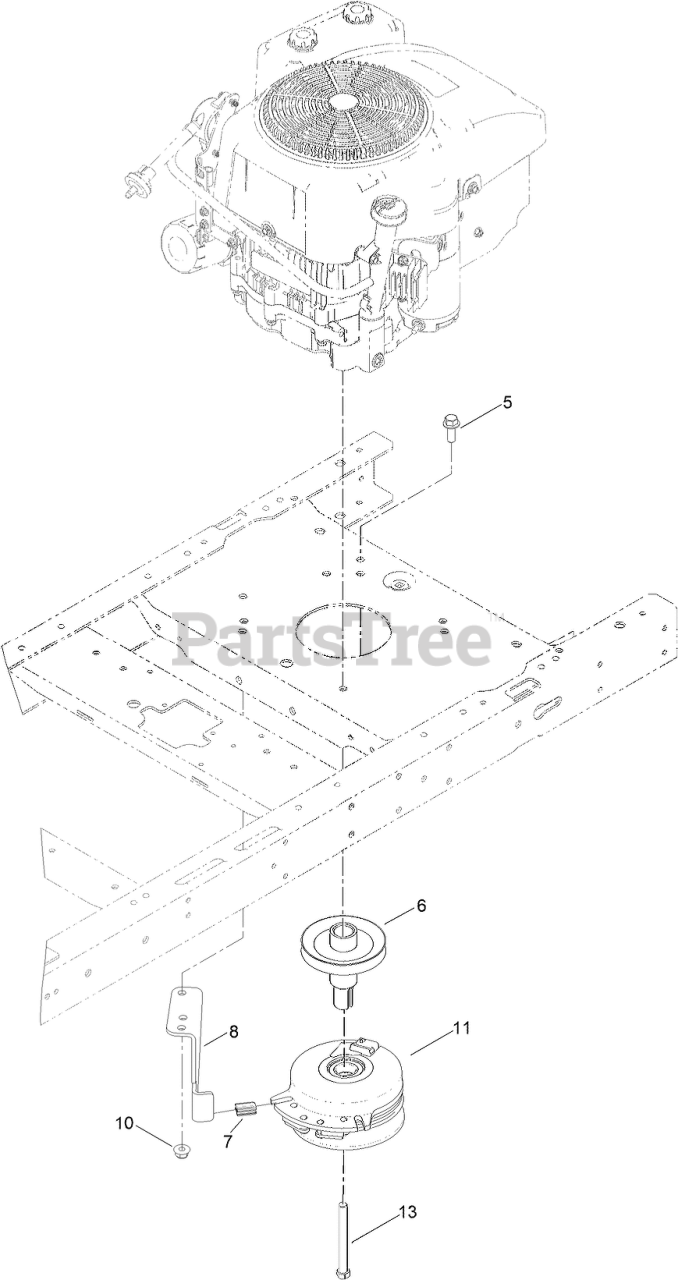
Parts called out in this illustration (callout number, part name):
5	SCREW-HHF
6	PULLEY-ENGINE
7	ISOLATOR-CLUTCH
8	STOP-CLUTCH
10	NUT-HF, NI
11	CLUTCH-ELECTRIC
13	SCREW-HH
